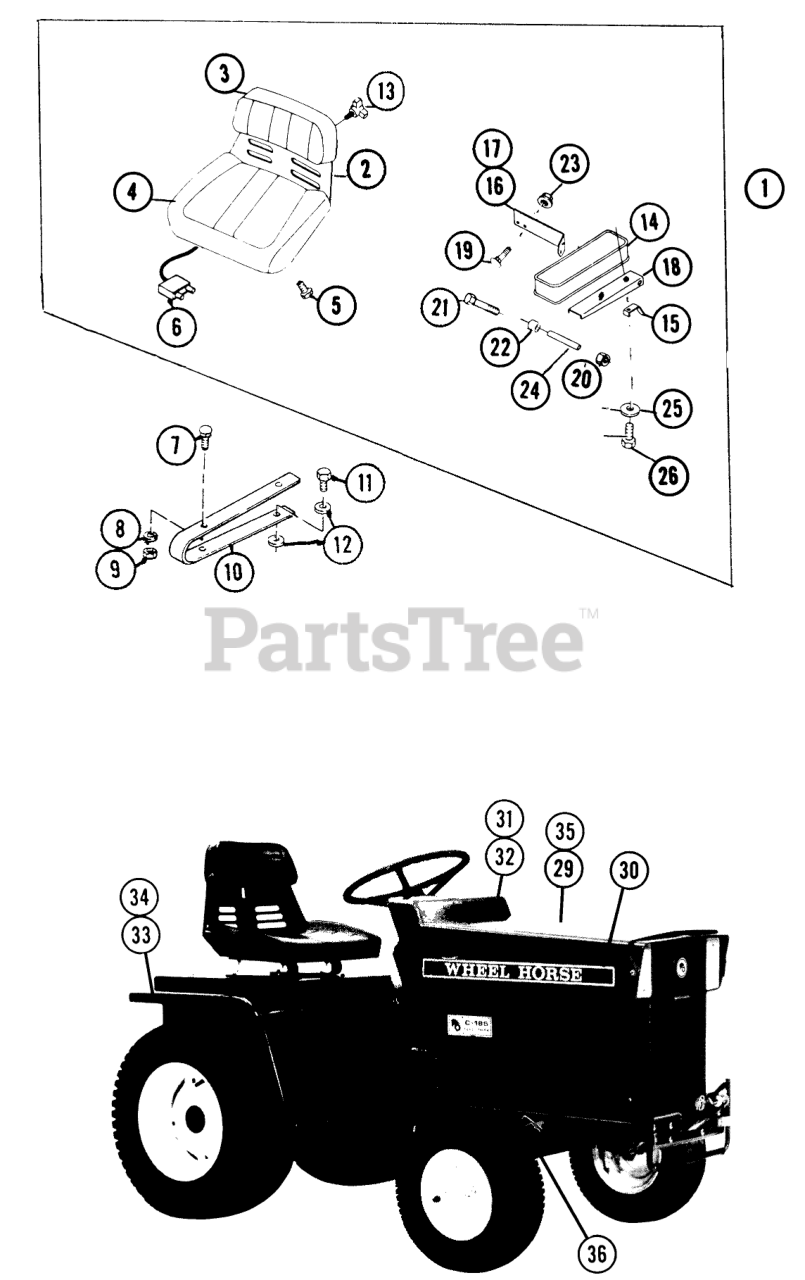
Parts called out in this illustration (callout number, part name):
15-01	Seat Assembly
15-02	Seat Base
15-03	Back Cushion
15-04	Seat Cushion Assembly, w/Switch
15-05	Screw
15-06	Pin Housing
15-07	Bolt
15-08	Washer 5/16
15-09	Nut
15-10	Spring
15-11	Bolt, Hex 5/16-18 x 1
15-12	Washer 5/16
15-13	Knob 8 HP
15-14	Arm Rest Pad
15-15	Arm Stop
15-16	Bracket-R.H.
15-17	Bracket-L.H.
15-19	Bolt-Carriage
15-20	Nut
15-21	Screw-Hex. Hd.
15-22	PIN-SPLIT ROLLED
15-23	NUT
15-24	Spacer
15-25	Lockwasher
15-26	Bolt
15-29	Decal, Hood
15-30	Decal
15-31	Fuse Decal
15-32	Decal, Dash/Instructions
15-33	DECAL-WHEEL HORSE
15-34	Reflector
15-35	Decal, Caution (Battery Covers)
15-36	Decal, C-185
